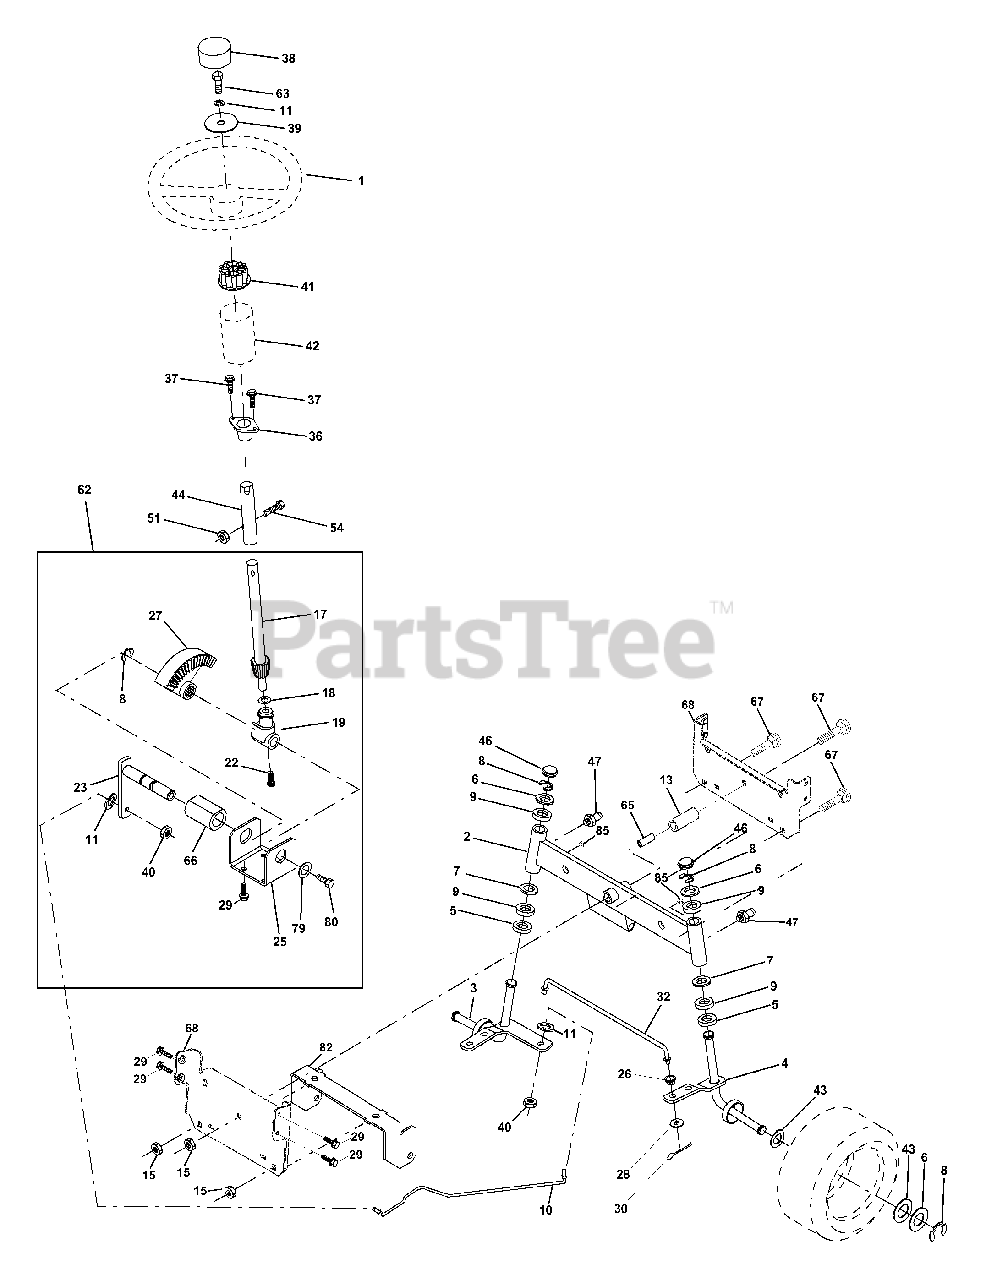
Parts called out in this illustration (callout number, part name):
1	Wheel Steering
2	Axle Asm STMP Dropped STL
3	Spindle Asm LH
4	Spindle Asm RH
5	Bearing Race Thrust Harden
6	Washer 25/32 X 1-5/8 X 16 Ga
7	Washer 27/32 X 1-1/4 X 16 Ga
8	Ring Klip #t5304-75
9	Bearing Col Strg Blk
11	Washer Lock Hvy Hlcl Spr 3/8
13	Spacer Brg Axle Front
15	Nut Hex Flange Lock
17	Shaft Asm Strg
18	Washer Thrust 515x 750x 033
19	Support Shaft
22	Screw Hex Wsh Hd Torx
23	Shaft Asm Pittman
25	Bracket Steering
26	Bushing Link Drag Blk LR
27	Gear Sector
28	Washer 13/32 X 7/8 X 16 Ga
29	Screw 3/8-16x3/4
30	Pin Cotter 1/8 X 3/4 Cad
32	Rod Tie Wire Form 19 75 Mech
36	Bushing Strg
38	Insert Cap Strg Wh Au
39	Washer 13/32 X 2-3/8 X 12 Ga
40	Lock nut
41	Adaptor Wheel Strg
42	Boot Steering Shaft
43	Washer 25/32 X 1 1/4 X 16 Ga
44	Extension Steering Shaft LR/LT
46	Cap Spindle Fr Top Blk
47	Fitting Grease
51	Nut Lock Hex w/Ins 5/16-18
54	Bolt Fin Hex 5/16-18 Unc x 1-1/4
62	Kit, Steering Assembly Svc
63	Bolt Fin Hex 3/8-16unc x 1 Gr. 5
65	Spacer Brace Axle
66	Bearing Arm Pittman
67	Bolt Rdhd Sqnk 3/8-16 x 2-1/4
68	Axle, Brace
79	Washer 13/32 x 1-1/4 x 12 Ga.
80	Bolt Hex Nylon 3/8-16 x 3/4
82	Bracket Susp Chassis Front
